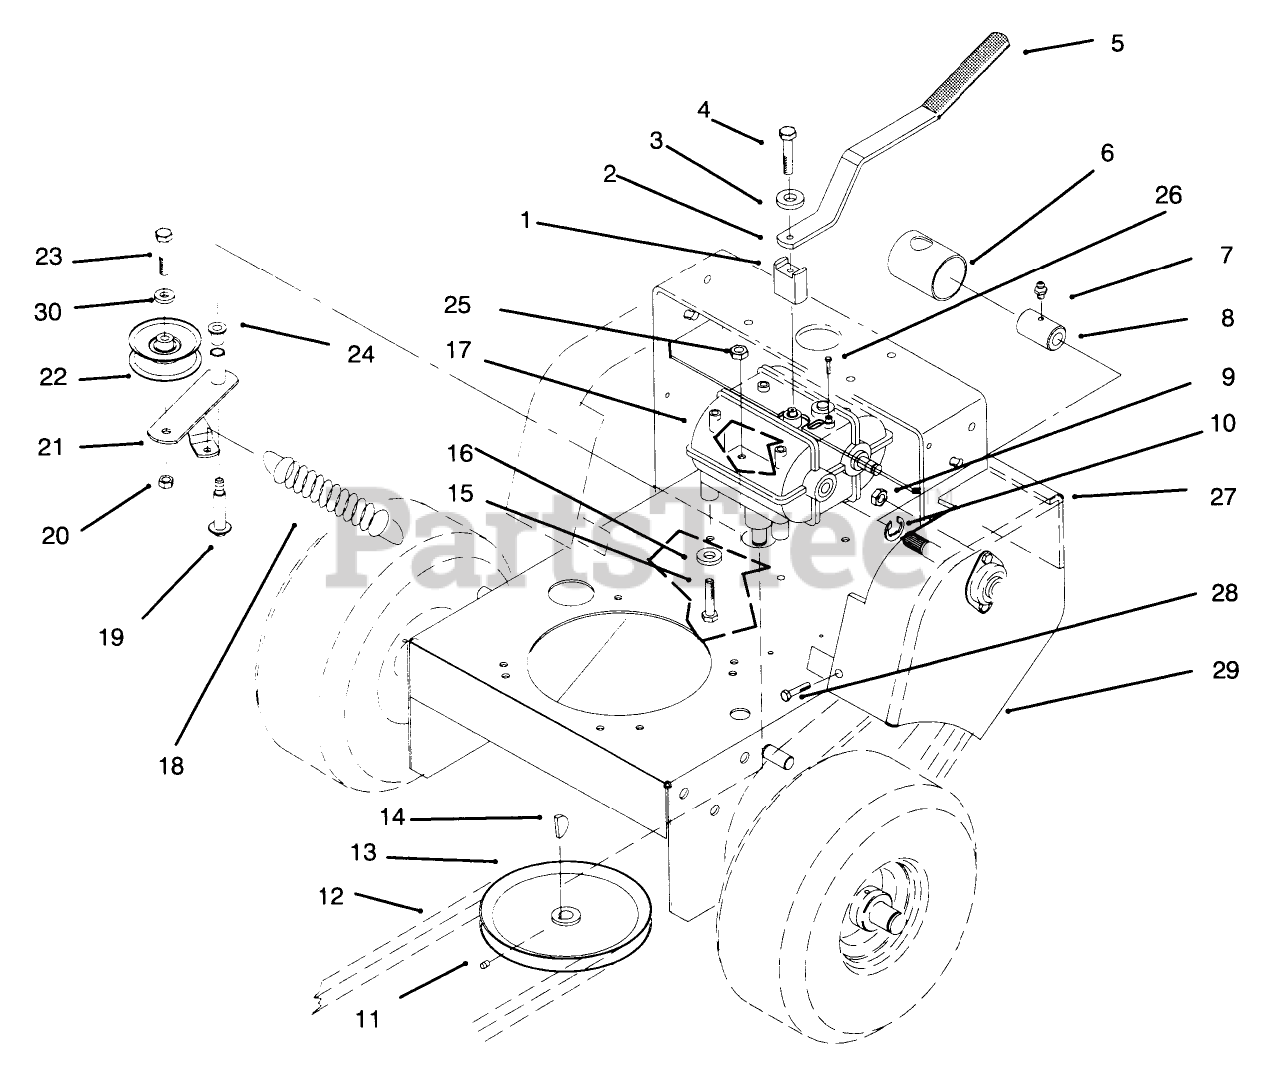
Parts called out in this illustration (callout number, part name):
1	MOUNT-LEVER, SHIFT
3	SPACER
4	SCREW-HH
6	GUARD-COUPLER
7	FITTING-GREASE
8	COUPLER
9	NUT-LOCK, NI
10	RING-SNAP, EXTERNAL
11	SCREW-SET
12	BELT V
13	PULLEY-DRIVEN
15	SCREW-HH
16	WASHER-LOCK
17	TRANSMISSION
18	SPRING
19	BOLT-WHEEL
20	NUT-LOCK, NI
22	PULLEY
23	SCREW-HH
24	BUSHING-FLANGE
25	NUT-LOCK
26	SCREW-HWHTF
28	SCREW
29	GUARD-BELT, LH
30	WASHER-FLAT
